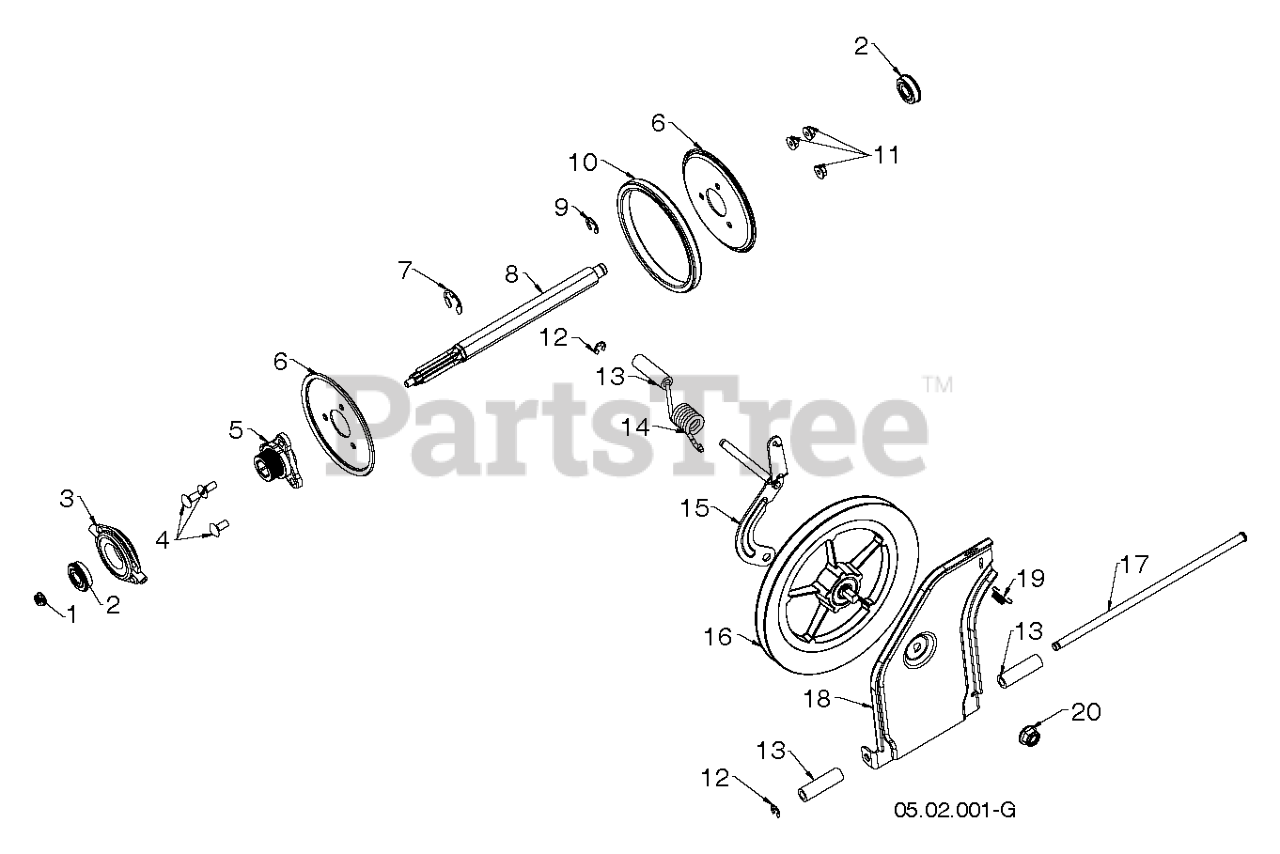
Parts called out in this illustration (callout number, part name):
1	NUT.HEX.FLANGE.LOCK.5/16-18
2	BEARING 9/16 ID. SNR
3	TRUNNION BEARING ASSY
4	Bolt, Carriage 5/16-18 UNC x 3/4 (AYP part number)
5	HUB.RUBBER.WHEEL
6	PLATE.RUBBER.WHEEL.BLACK
7	E-Ring Truarc #5133-87 (AYP part number)
8	SHAFT SHAFT,7T REDUCTION
9	RING RING, RETAINING RING (996
10	RING RUBBER
11	NUT.LOCK.5/16-18
12	E-RING LT
13	SPACER YOKE, TORSION SPRING
14	SPRING TORSION DRIVE
15	BRACKET.YOKE.ASSEMBLY.479
16	PULLEY.FRICTION.DISC.COMBO
17	ROD.TIP.PLATE
18	PLATE.SWING.FRICTION PULLEY.47
19	SPRING LATCH
20	NUT, 1/2-13 HEX FLG NYLOC ZD
